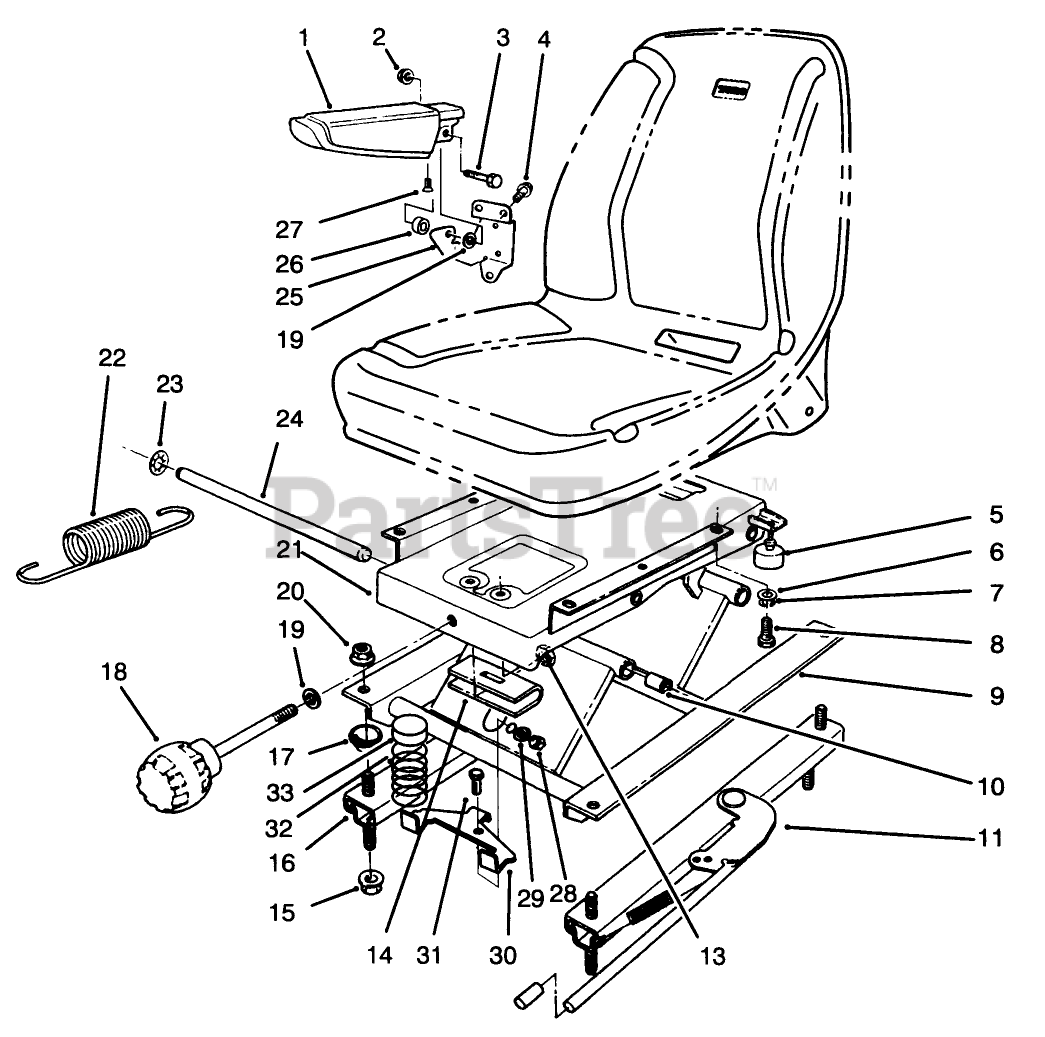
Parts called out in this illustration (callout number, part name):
1	ARMREST
2	NUT-HF
3	SCREW-HH
4	SCREW-HHF
5	BUMPER
6	WASHER-FLAT
7	WASHER-LOCK
8	SCREW-HH
9	FRAME-LOWER
10	SLEEVE-BEARING
11	ADJUSTER W / HANDLE
13	NUT-LOCK, SIDE
14	Hanger-Spring
15	NUT-LOCK, NI
16	ADJUSTER
17	SPACER-SUSPENSION
18	KNOB-ADJUSTER, TENSION
19	WASHER-FLAT
20	NUT-HF
21	FRAME-UPPER
22	SPRING-EXTENSION
23	NUT-PUSH
24	SHAFT-PIVOT
25	SPACER
26	BRACKET-ARM, RH
27	SCREW
28	NUT-HEX
29	WASHER-LOCK
30	BRACKET
31	SCREW-HH
32	SPRING
